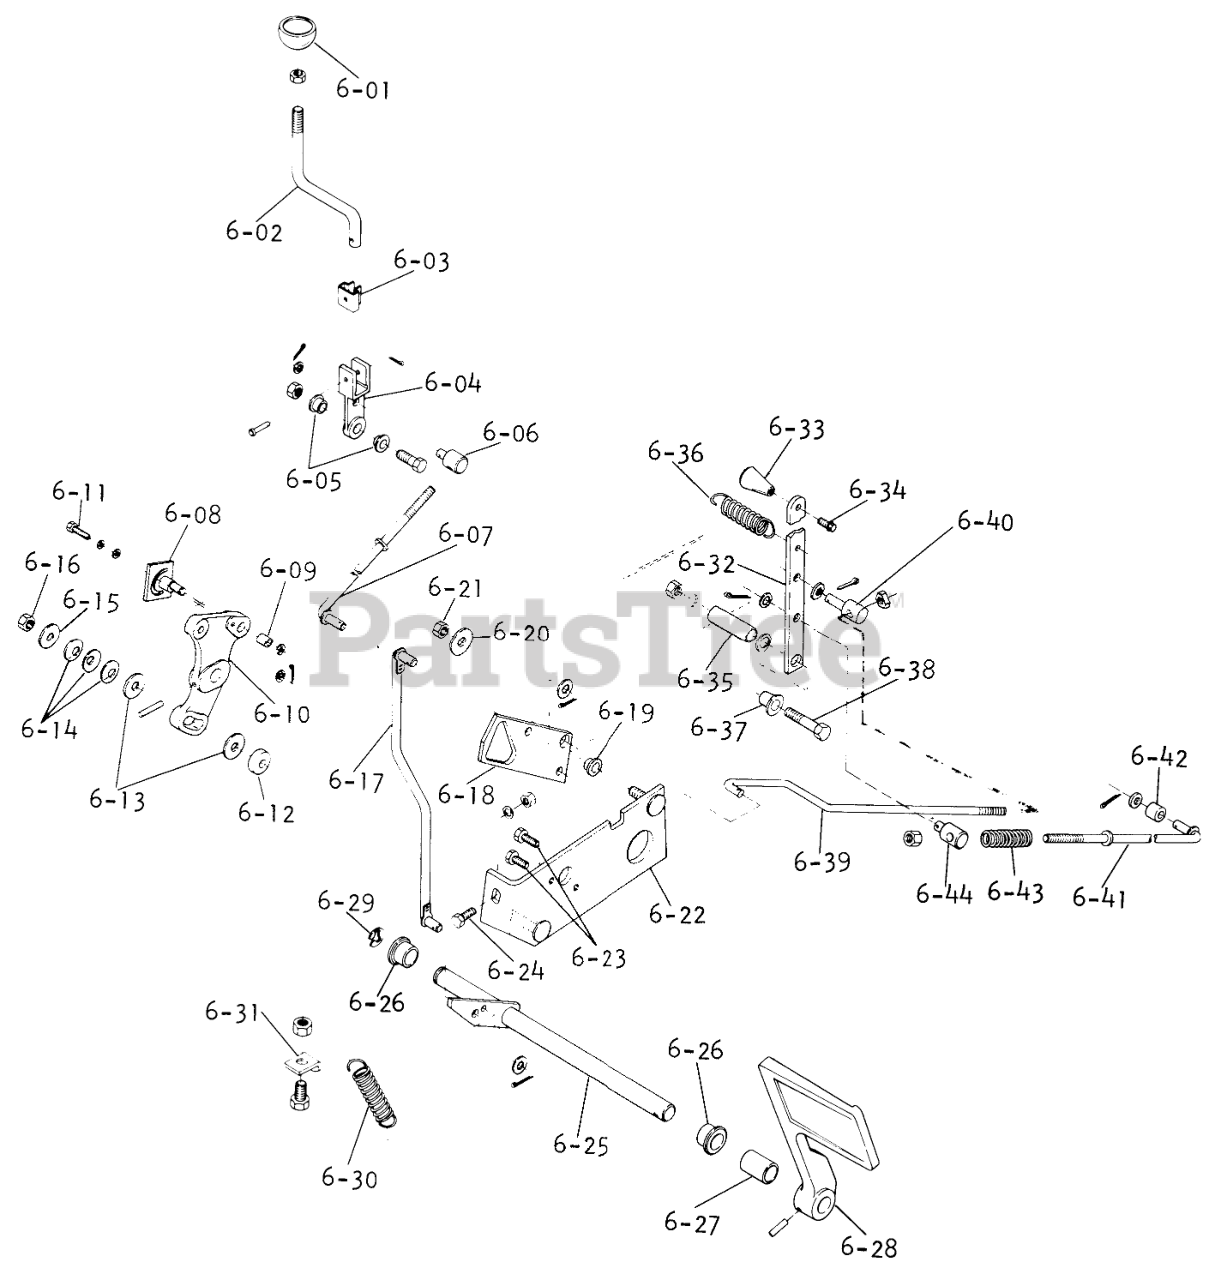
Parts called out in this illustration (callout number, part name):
6-02	HANDLE
6-03	Spring
6-04	Pivot
6-05	CAM-SPACER
6-06	TRUNNION
6-07	Rod Assy.
6-08	Eccentric Assy.
6-09	Spacer
6-11	Bolt-Hex slot 1/4-20 X 1/2
6-12	SPACER
6-13	FRICTION WASHER
6-14	WASHER-SPRING DISC
6-15	Washer
6-16	3/8-16 E.S.
6-17	Rod-Neutral Pedal
6-18	Plate-Neutral Return
6-19	CAM-SPACER
6-20	WASHER
6-21	3/8-16 E.S.
6-22	Plate Assy.
6-23	Bolt 1/4-20 x 5/8 Whizlock
6-24	Bolt, 5/16-18 X 7/8
6-25	Assy-Shaft
6-26	BEARING
6-27	Spacer
6-28	Brake Pedal
6-29	E-RING
6-30	SPRING-EXTENSION
6-31	CLIP - SPRING
6-32	Handle-Parking Brake
6-34	Bolt, 1/4-20 Whizlock
6-35	Spacer
6-36	Spring
6-37	CAM-SPACER
6-38	Bolt Hex 3/8-16 x 1
6-39	Rod-Brake Handle to Neutral Cam
6-40	TRUNNION-LIFT
6-41	Rod Assy.
6-42	SPACER
6-43	Spring
6-44	TRUNNION-LIFT
